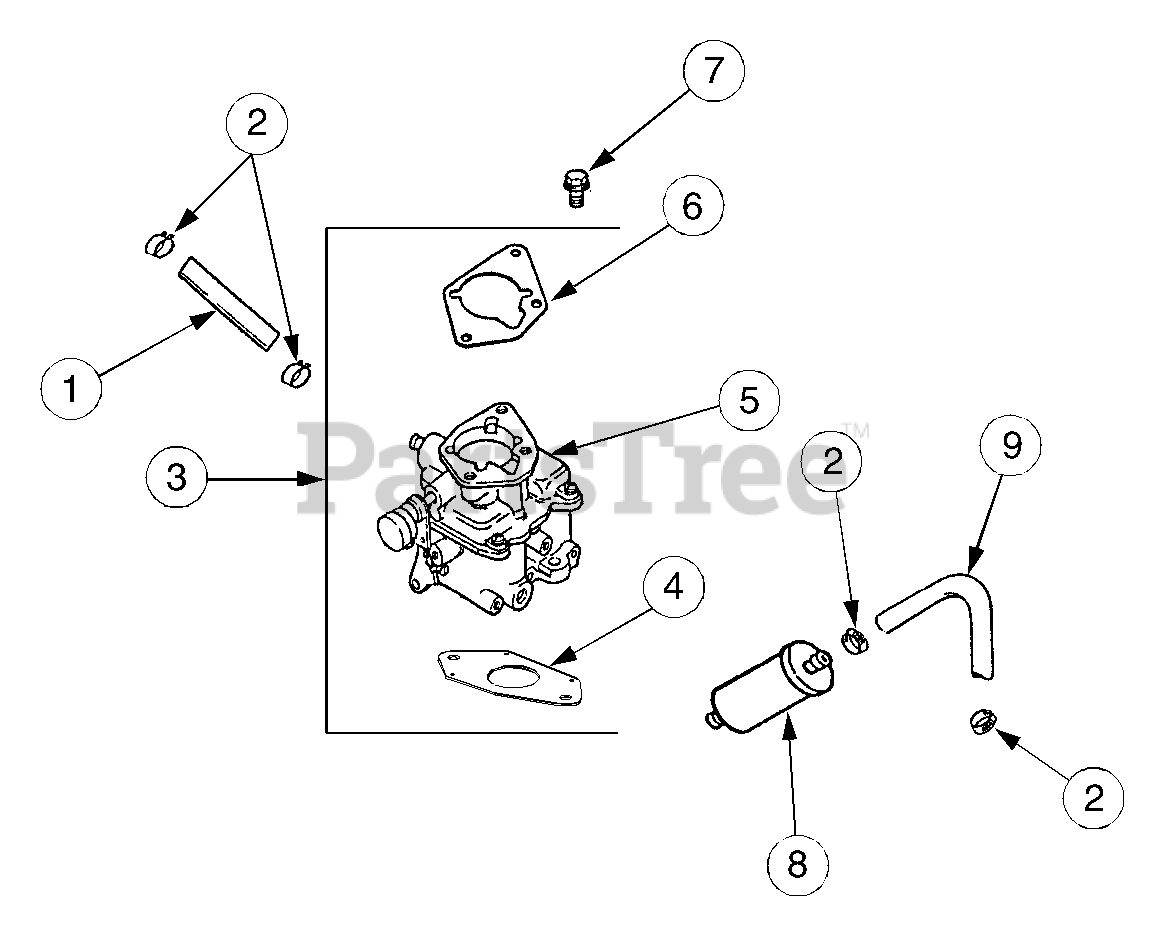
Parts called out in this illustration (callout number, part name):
1	Line, Fuel 9-1/4"
2	Clamp, Hose
3	Kit, Carburetor w/Gasket
4	Gasket, Carburetor
5	Carburetor Assembly
6	Gasket, Air Cleaner Base
7	Screw, Hex Flange, M6 x 1.0 x 25
8	Filter, Fuel
9	Line, Fuel 11"
